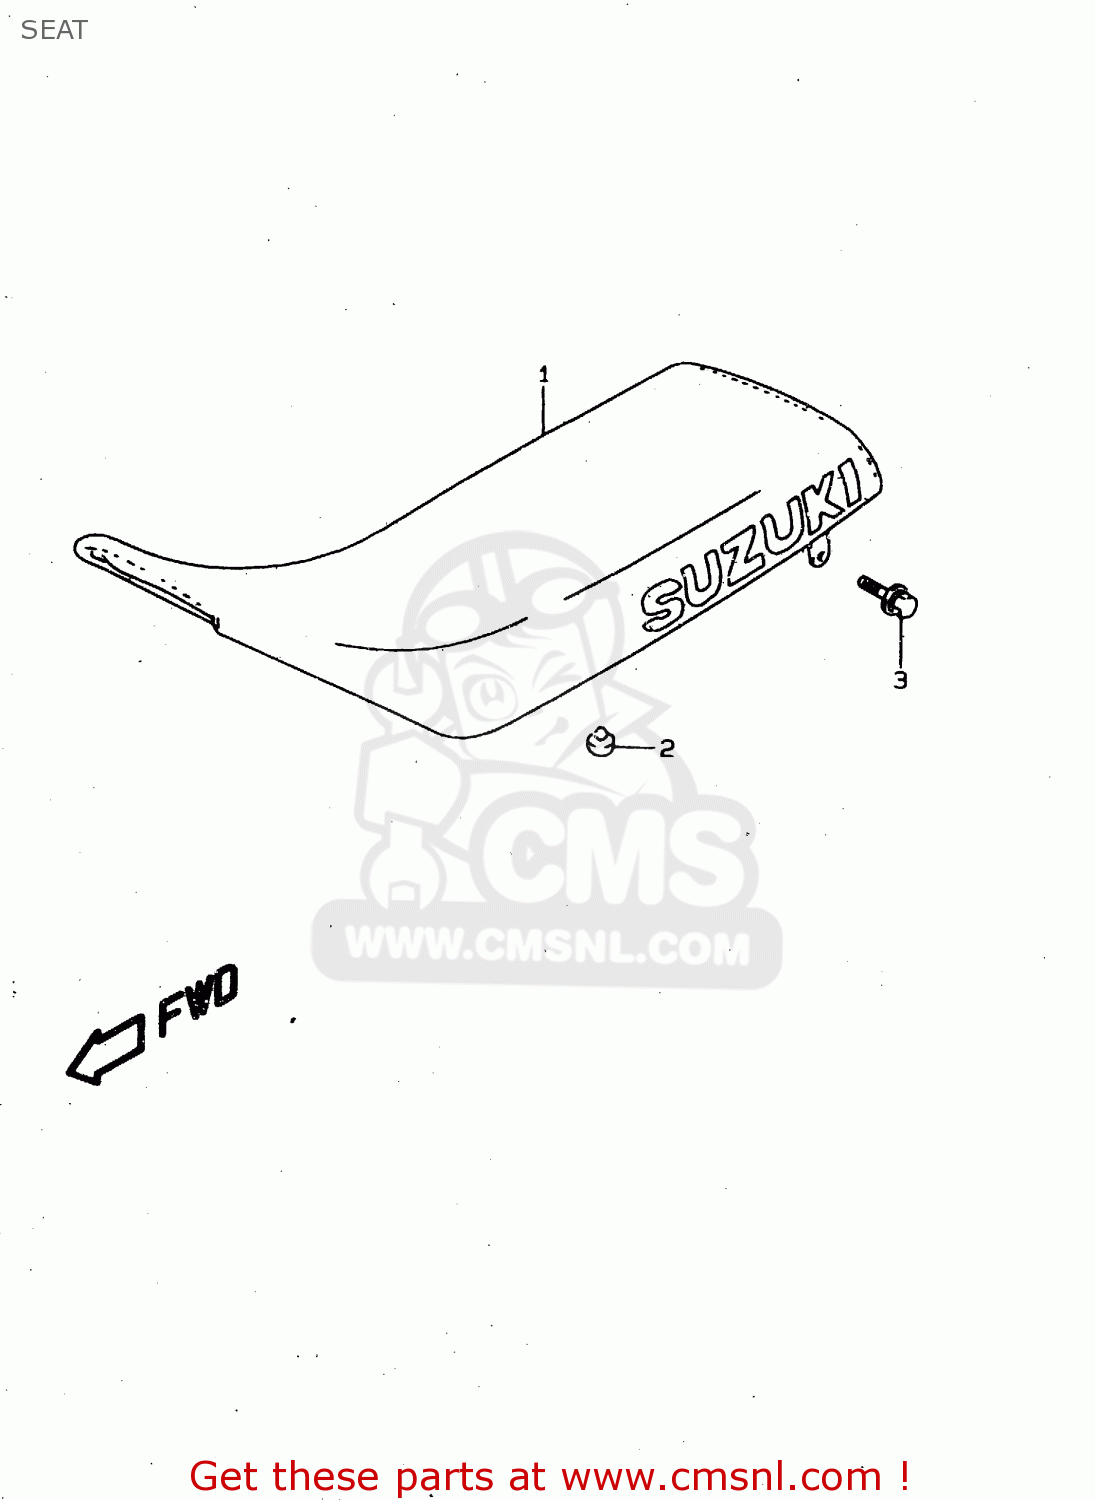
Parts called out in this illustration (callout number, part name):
1	SEAT SET
2	CUSHION
3	BOLT
